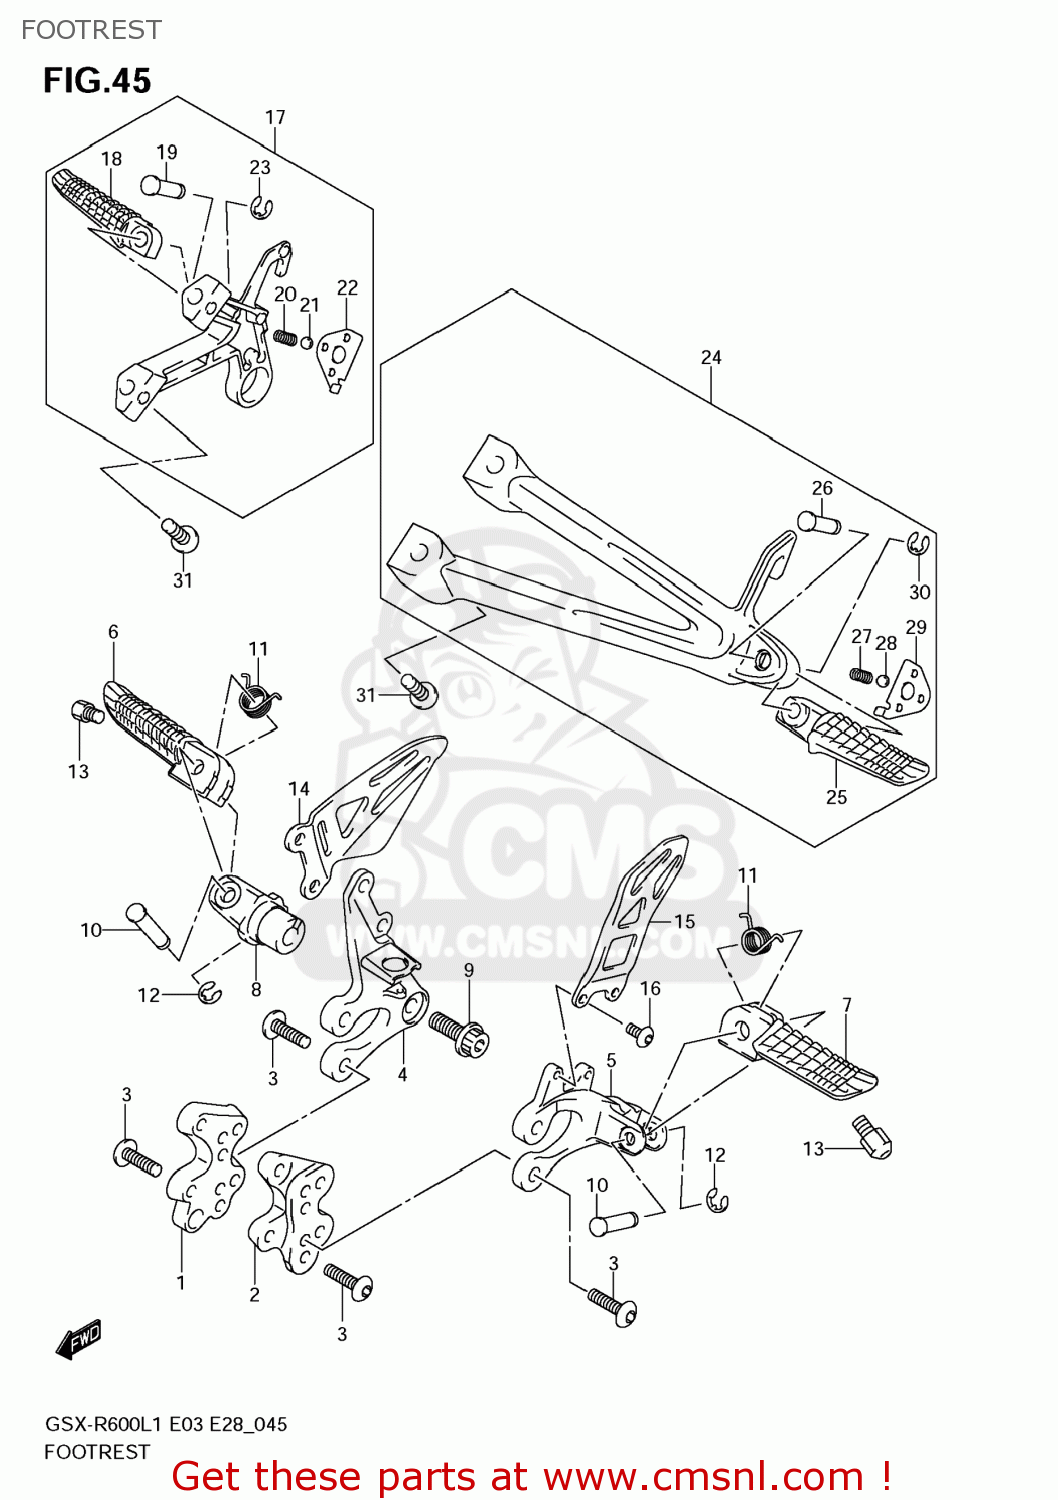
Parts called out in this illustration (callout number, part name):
1	BRACKET,FR FOOTREST NO.1,R
2	BRACKET,FR FOOTREST NO.1,L
3	BOLT(8X23)
4	BRACKET,FR FOOTREST NO.2,R
5	BRACKET,FR FOOTREST NO.2,L
6	BAR,FR FOOTREST,R
7	BAR,FR FOOTREST,L
8	HOLDER,FOOTREST
9	BOLT(10X28)
10	PIN
11	SPRING
12	E RING
13	BOLT,BANK SENSOR
14	GUARD,FR FOOTREST,R
15	GUARD,FR FOOTREST,L
16	SCREW,FOOTREST GUARD,L
17	FOOTREST ASSY,PILLION,R
18	BAR,PILLION FOOTREST,R
19	PIN
20	SPRING
21	BALL
22	PLATE,PILLION FOOTREST,R
23	E RING
24	FOOTREST ASSY,PILLION,L
25	BAR,PILLION FOOTREST,L
26	PIN
27	SPRING
28	BALL
29	PLATE,PILLION FOOTREST,L
30	E RING
31	BOLT(8X23)
